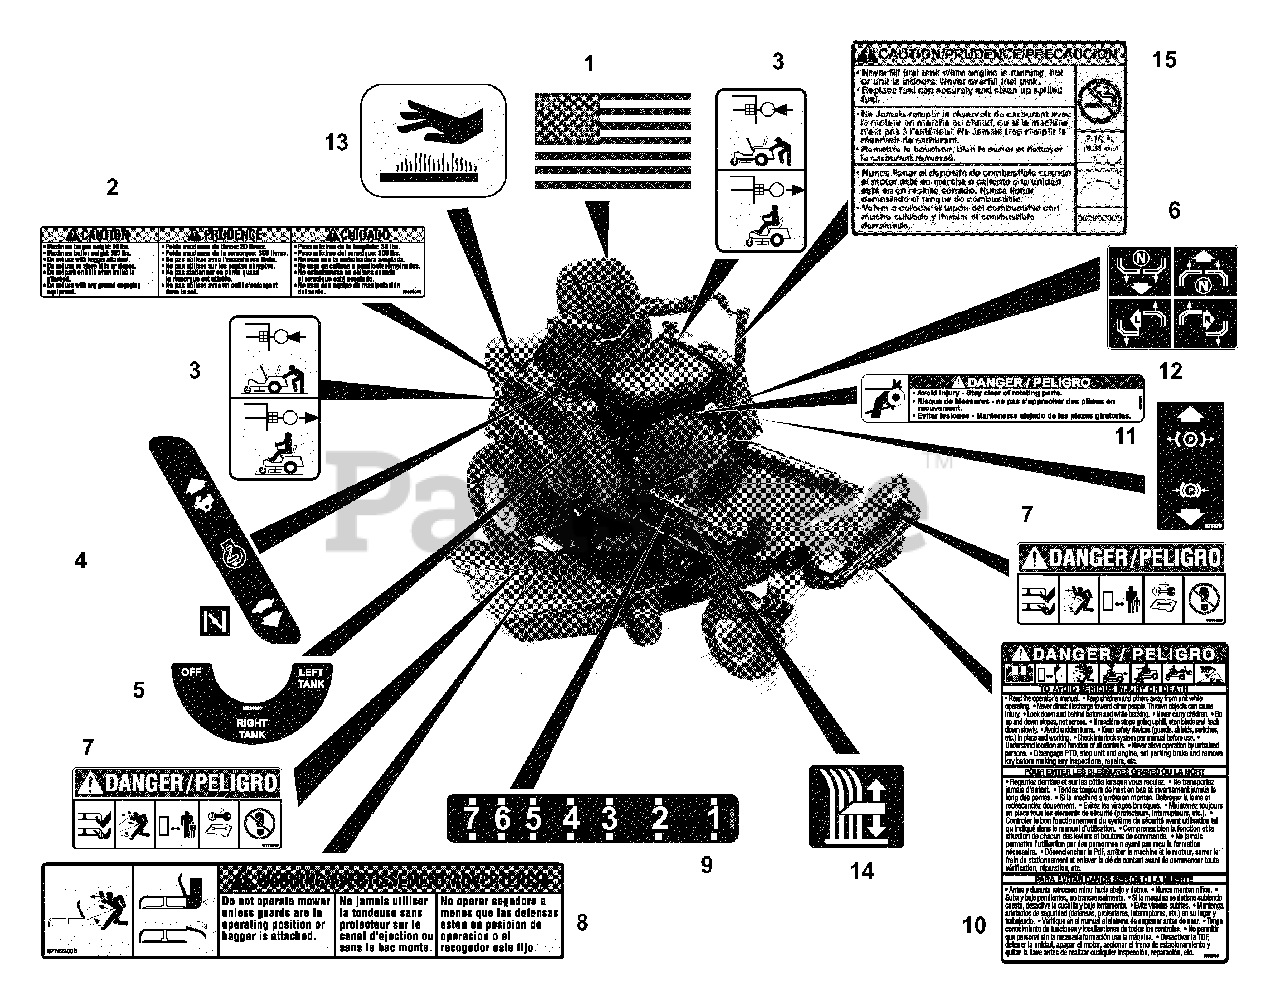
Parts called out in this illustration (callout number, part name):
1	DECAL, AMERICAN FLAG
2	DECAL, TRAILER HITCH
3	DECAL, TRANSMISSION DISCONNECT
4	DECAL, SPEED CONTROL
5	DECAL, FUEL VALVE
6	DECAL, INSTRUCTIONAL-STEERING
7	DECAL, MOWER PAN DANGER
8	DECAL, WARNING
9	DECAL CUT HEIGHT
10	DECAL, DANGER BILINGUAL
11	DECAL, PARKING BRAKE LEVER
12	DECAL- DANGER
13	DECAL, HOT SURFACE
14	DECAL-CUT HEIGHT
15	DECAL,FUEL WARNING
